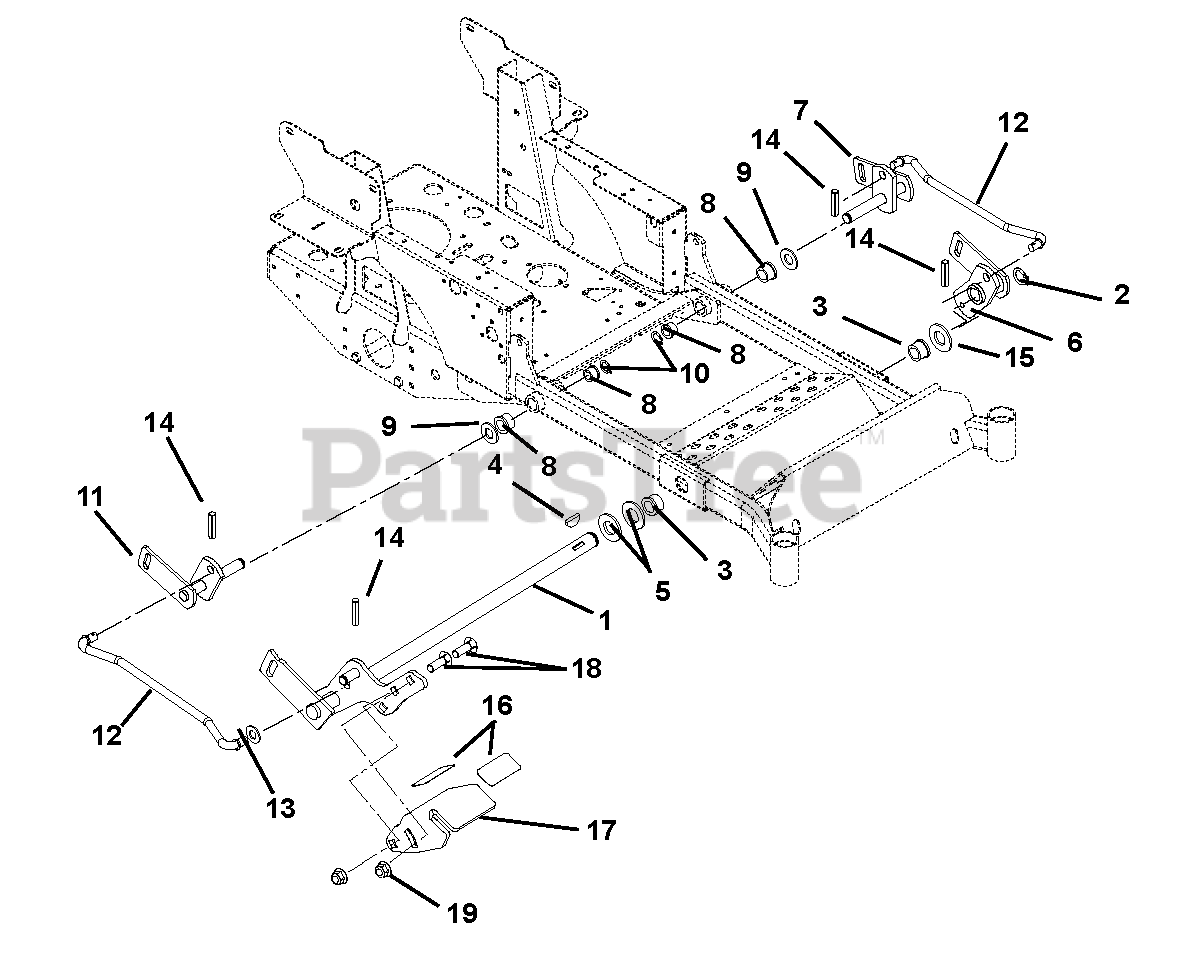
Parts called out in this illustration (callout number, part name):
1	Weldment, Mechanical Deck Lift
2	Ring, Retaining External 1.00 x .078
3	Bushing, Flange Nylon 1.020 x 1.385 x .75 x 1.75
4	Key, Woodruff .25 x 1.00
5	Washer, Flat Steel 1.062 x 2.0 x .134
6	Weldment, Left Hand Mower Lift Arm
7	Weldment, Left Hand Rear Mower Lift Arm
8	Bushing, Flange Nylon .762 x 1.0 x .580 x 1.48
9	Washer, Hardened Steel .758 x 1.23 x .031
10	Ring, Retaining External .689 x .077
11	Weldment, Right Hand Rear Mower Lift Arm
12	Rod, Lift Assist
13	Washer, Flat Steel .630 x 1.25 x .062
14	Pin, Roll .25 x 1.25 Stainless Steel
15	Washer, Hardened Thrust 1.00 x 1.55 x .03
16	Grip, Pedal
17	Foot Pedal, Adjustable Black
18	Bolt, Round Hd. Square Neck .50-13 x 1.50 Grade 5 YZ
19	Nut, Locking Top Flange .50-13
